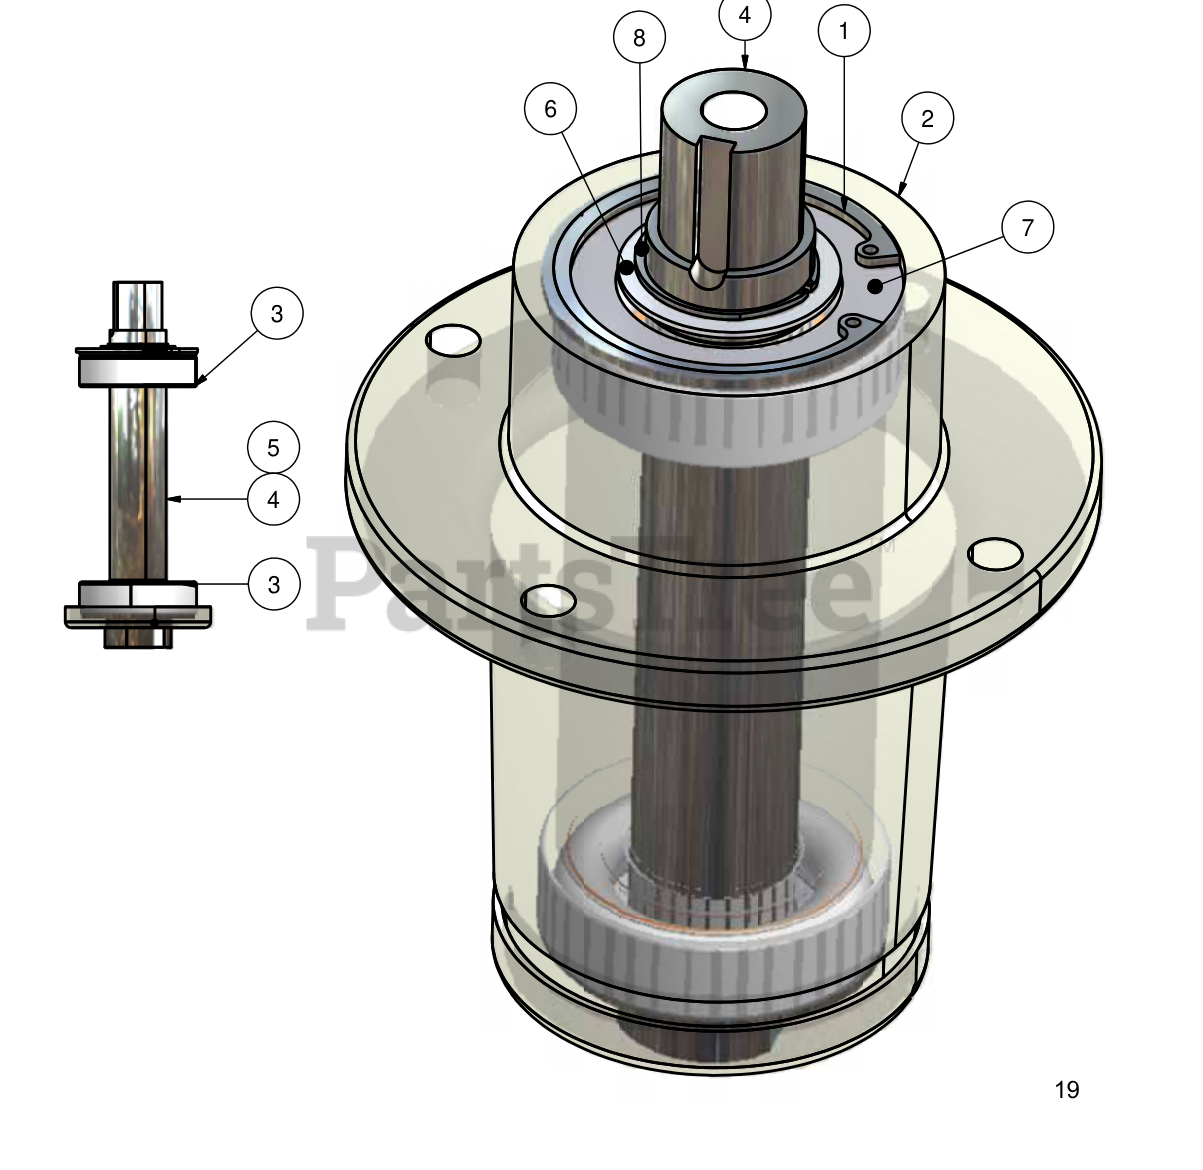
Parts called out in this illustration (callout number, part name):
1	Bearing Retainer Ring
2	Spindle Housing
4	Short Shaft
5	Long Shaft
6	Small Bearing Spacer
7	Large Bearing Spacer
8	Shaft Retainer Ring
